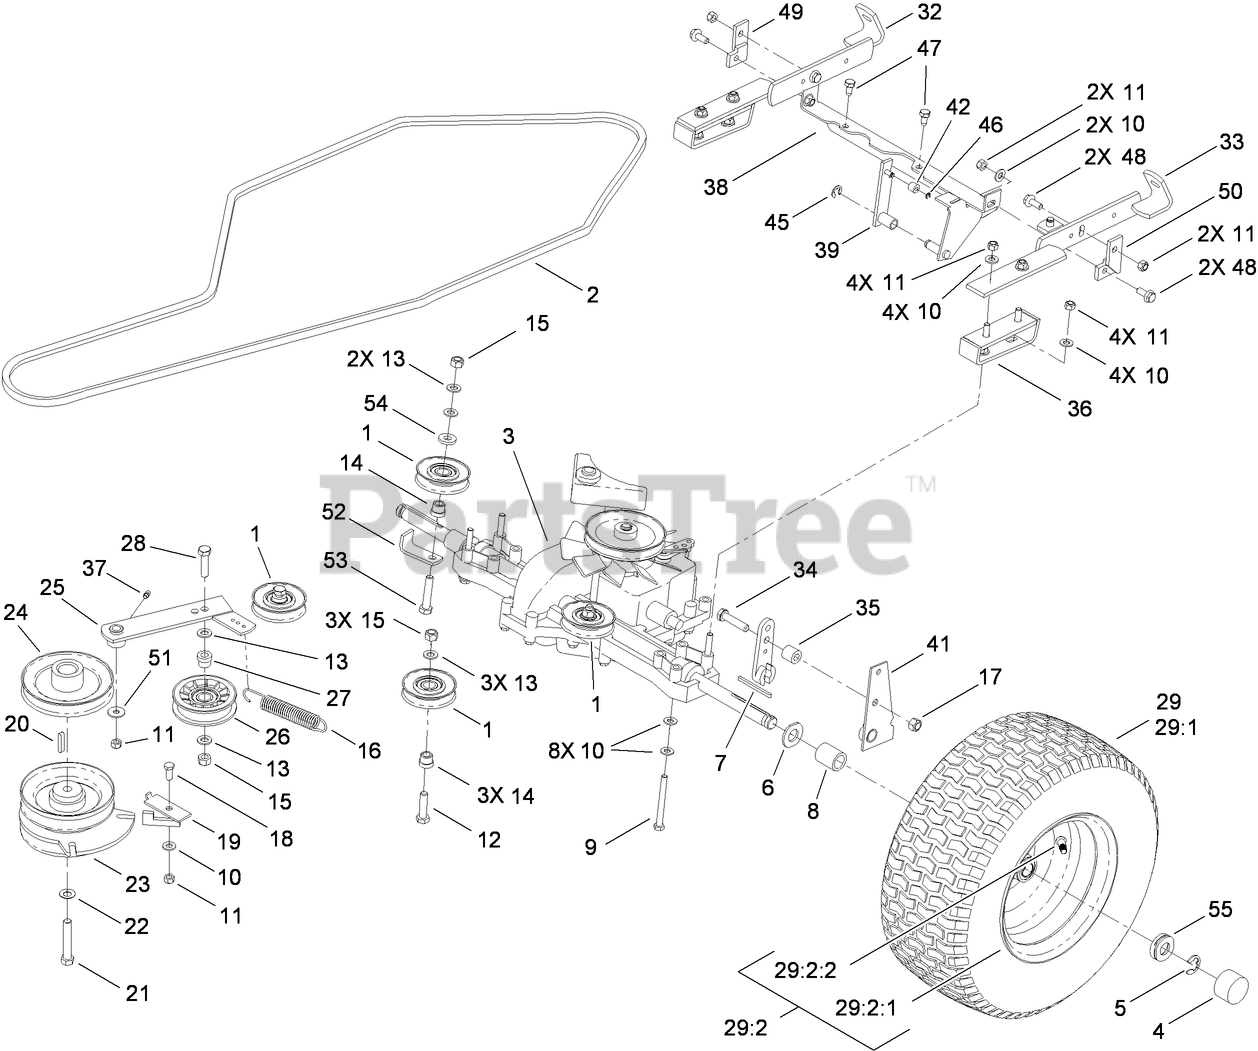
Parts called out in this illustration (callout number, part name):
1	PULLEY-IDLER
2	V-BELT-TRACTION
3	TRANSMISSION
4	CAP-HUB
5	CLIP-SPRING
6	WASHER
7	KEY-SQUARE
8	SPACER-AXLE
9	SCREW-HH
10	WASHER-PLAIN
11	NUT-LOCK, NI
12	SCREW-HH
13	WASHER-FLAT
14	BUSHING-IDLER
15	NUT-LOCK, NI
16	SPRING
17	NUT-LOCK, NI
18	SCREW-HH
19	RETAINER
20	KEY-SQUARE
21	SCREW-HH
22	WASHER-SPRING, BELLEVILLE
23	CLUTCH-ELECTRIC
24	PULLEY-ENGINE
25	ARM-IDLER
26	PULLEY-IDLER
27	BUSHING-IDLER
28	SCREW-HH
29	Loose Parts Package
29:1	TIRE
29:2	WHEEL ASM
29:2:1	Loose Parts Package
29:2:2	Valve-Tire
32	Bracket-Right
33	Bracket-Left
34	SCREW-HH
35	SLEEVE
36	BRACKET-SUPPORT
37	FITTING-GREASE
38	Bar ASM
42	Roller
45	Stirrup
46	STIRRUP
47	SCREW-THREAD FORMING
48	SCREW-HEX
49	BRACKET-RIGHT
50	BRACKET-LEFT
51	WASHER-PLAIN
52	RETAINER-BELT
53	SCREW-HH
54	WASHER-FLAT
55	RETAINER-CAP, HUB
